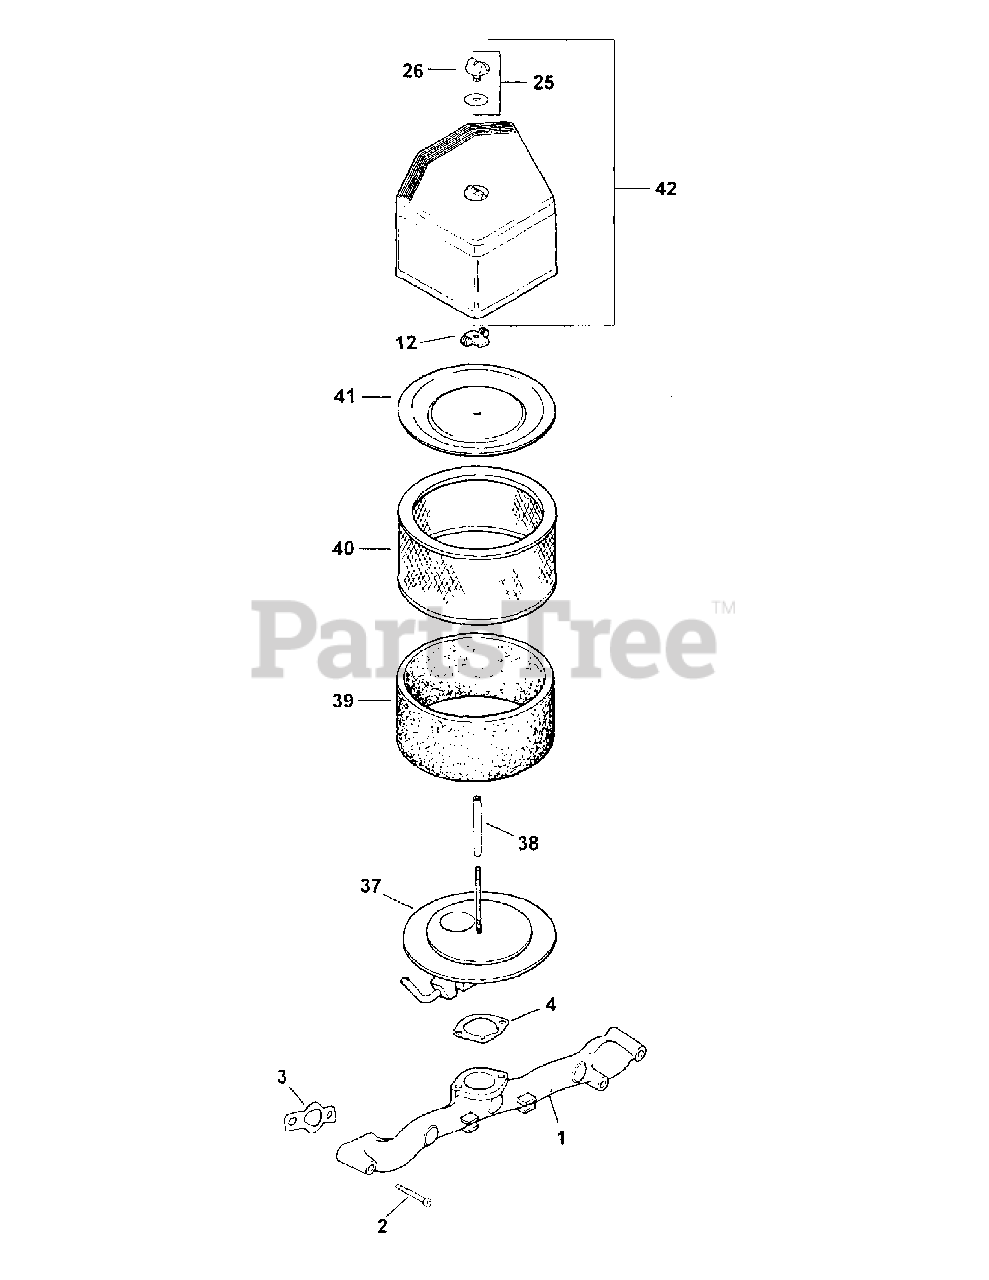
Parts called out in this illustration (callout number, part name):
1	Manifold, Intake
2	Screw, Hex Flange
3	Gasket, Intake Manifold
4	Gasket, Air Cleaner Base
12	Nut, Wing
25	Kit, Air Cleaner Knob w/Gasket
26	Knob, Air Cleaner Cover
37	Elbow, Air Cleaner
39	Element, Precleaner
40	Elements, Air Cleaner & Precleaner
41	Cover, Air Cleaner Element
42	Kit, Air Cleaner Cover
